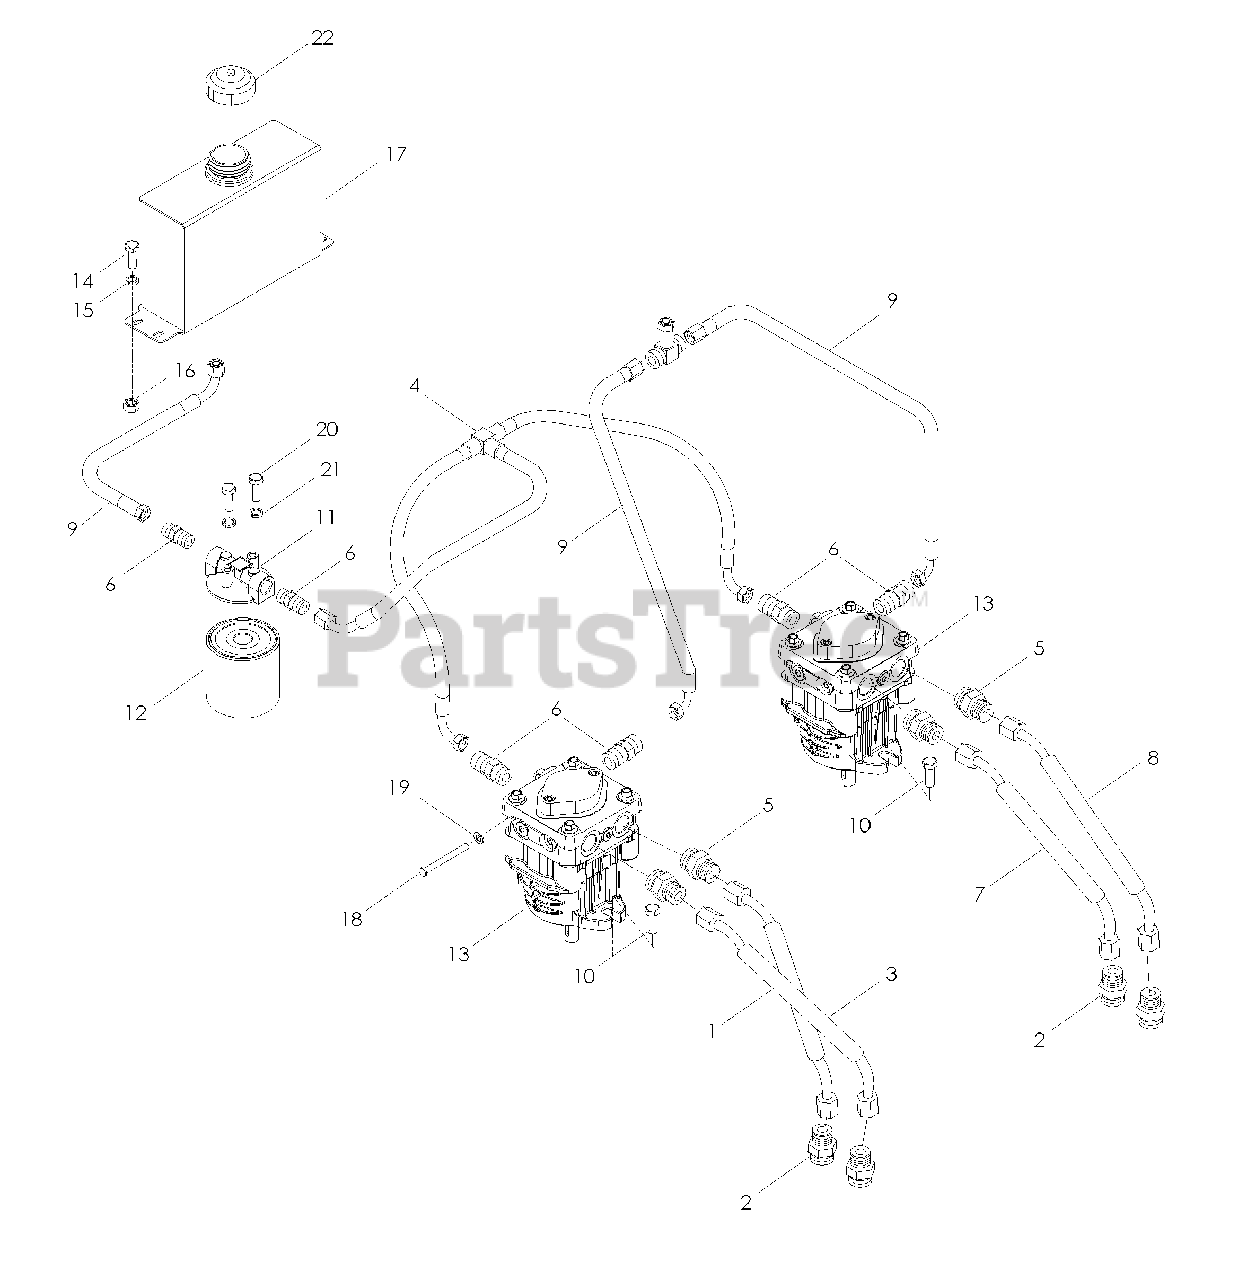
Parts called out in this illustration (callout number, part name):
2	FITTING, STRAIGHT
5	FITTING, STRAIGHT
6	CONNECTOR, STRAIGHT
9	HOSE, RETURN
10	HCS 3/8-16 x 1
11	FILTER HEAD
13	PUMP W/O FAN
14	HCS 1/4-20 x 3/4
15	WASHER 1/4
16	NUT 1/4-20 CNTRLK
18	PIN, CLEVIS
20	HCS 1/4-20 x 5/8
21	LOCKWASHER 1/4
